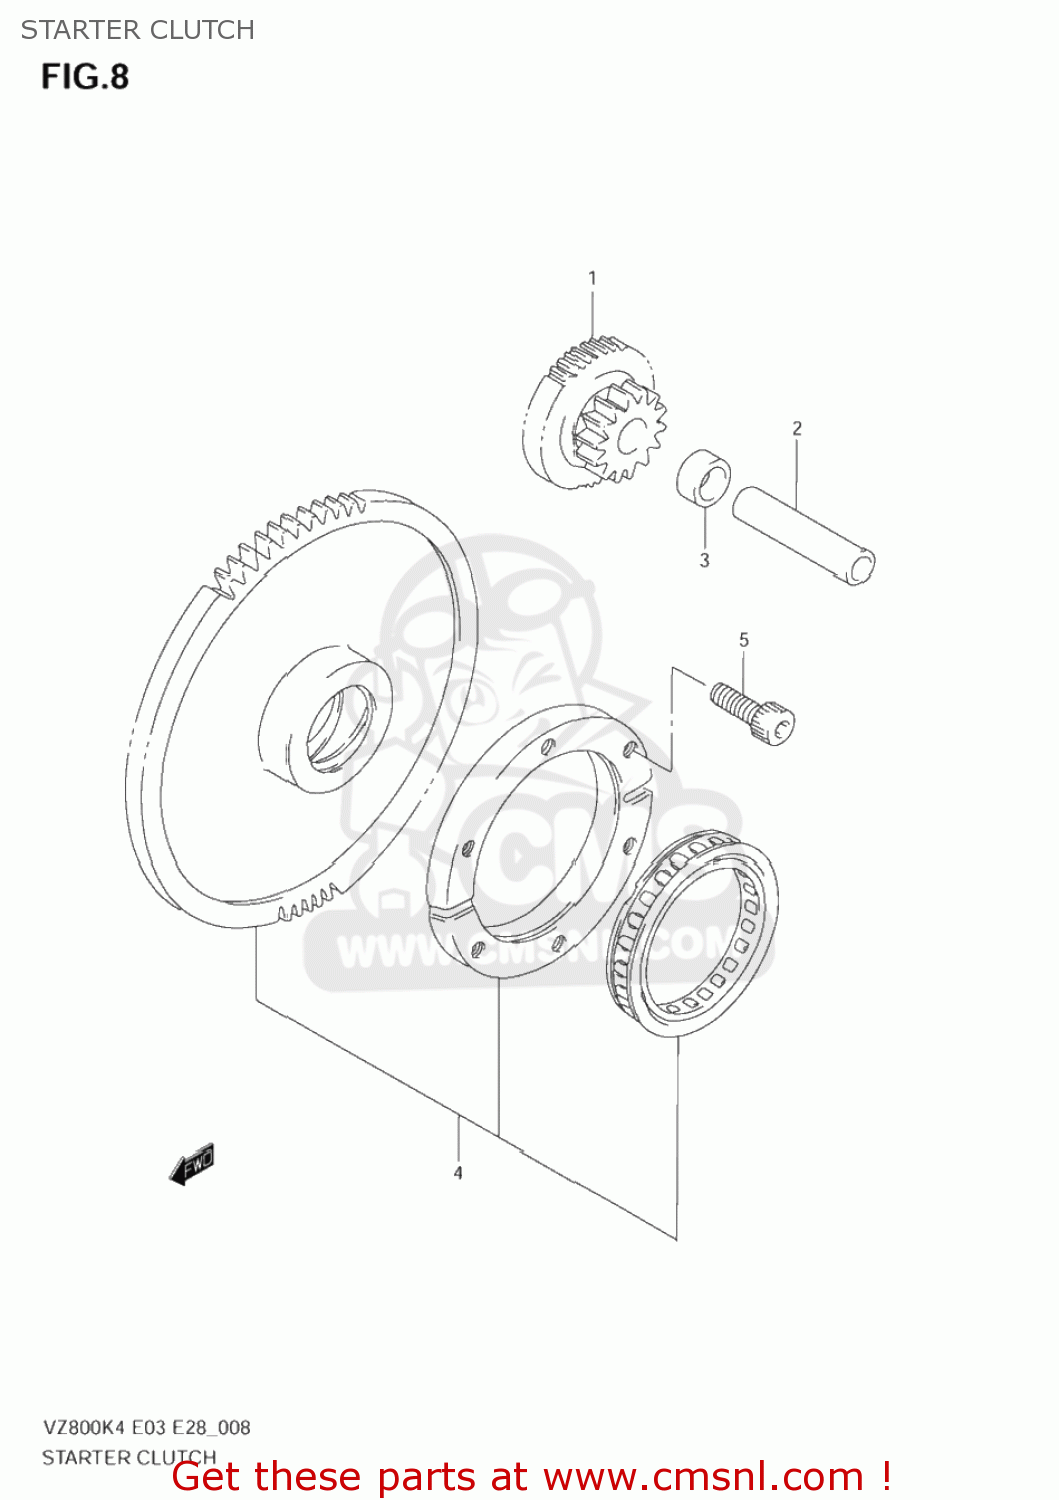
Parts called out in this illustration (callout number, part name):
1	GEAR,STARTER IDLE(NT:14/49)
2	PIN(12X55.5)
3	SPACER(12.5X19X9.5)
4	CLUTCH SET,STARTER
5	BOLT
